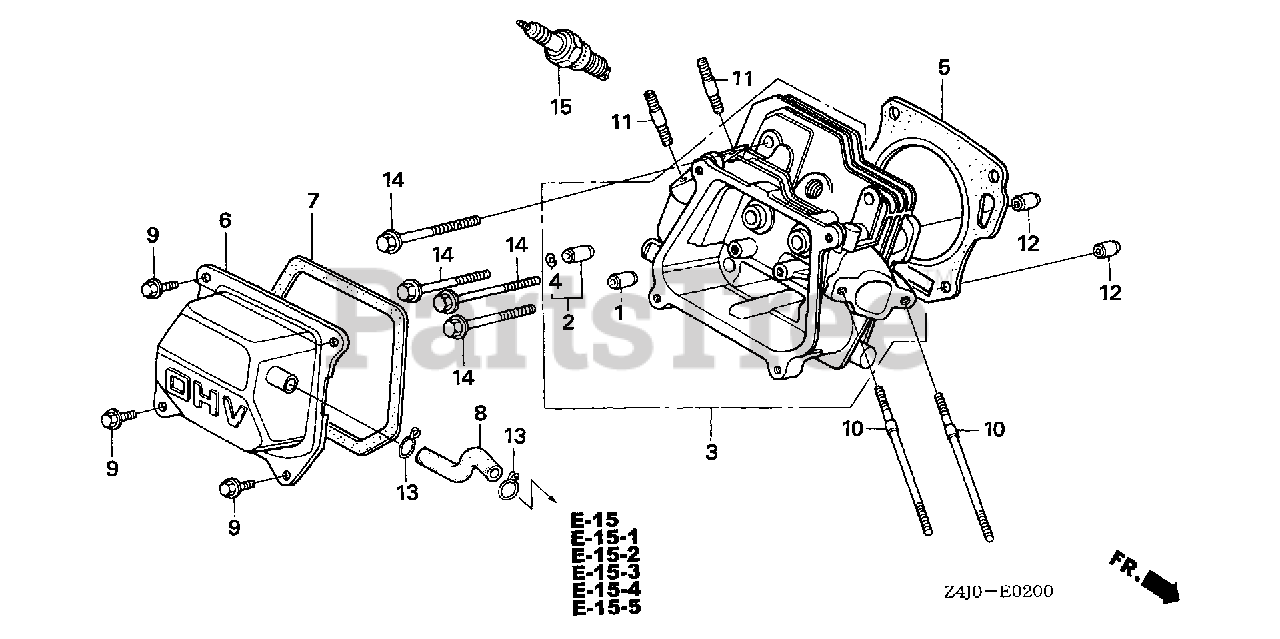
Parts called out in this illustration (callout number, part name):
1	GUIDE, VALVE (OVER SIZE)
2	GUIDE, EX. VALVE (OVER SIZE)
3	CYLINDER HEAD
4	CLIP, VALVE GUIDE
5	GASKET, CYLINDER HEAD
6	COVER, HEAD
7	GASKET, HEAD COVER
8	TUBE, BREATHER
9	BOLT, FLANGE (6X12) (CT200)
10	BOLT, STUD (6X112)
11	BOLT, STUD (8X32)
12	PIN, DOWEL (10X16)
14	BOLT, FLANGE (8X60)
15	SPARK PLUG (BPR5ES) (NGK)
15	SPARK PLUG (W16EPR-U) (DENSO)
15	SPARK PLUG (BPR6ES) (NGK)
15	SPARK PLUG (W20EPR-U) (DENSO)
